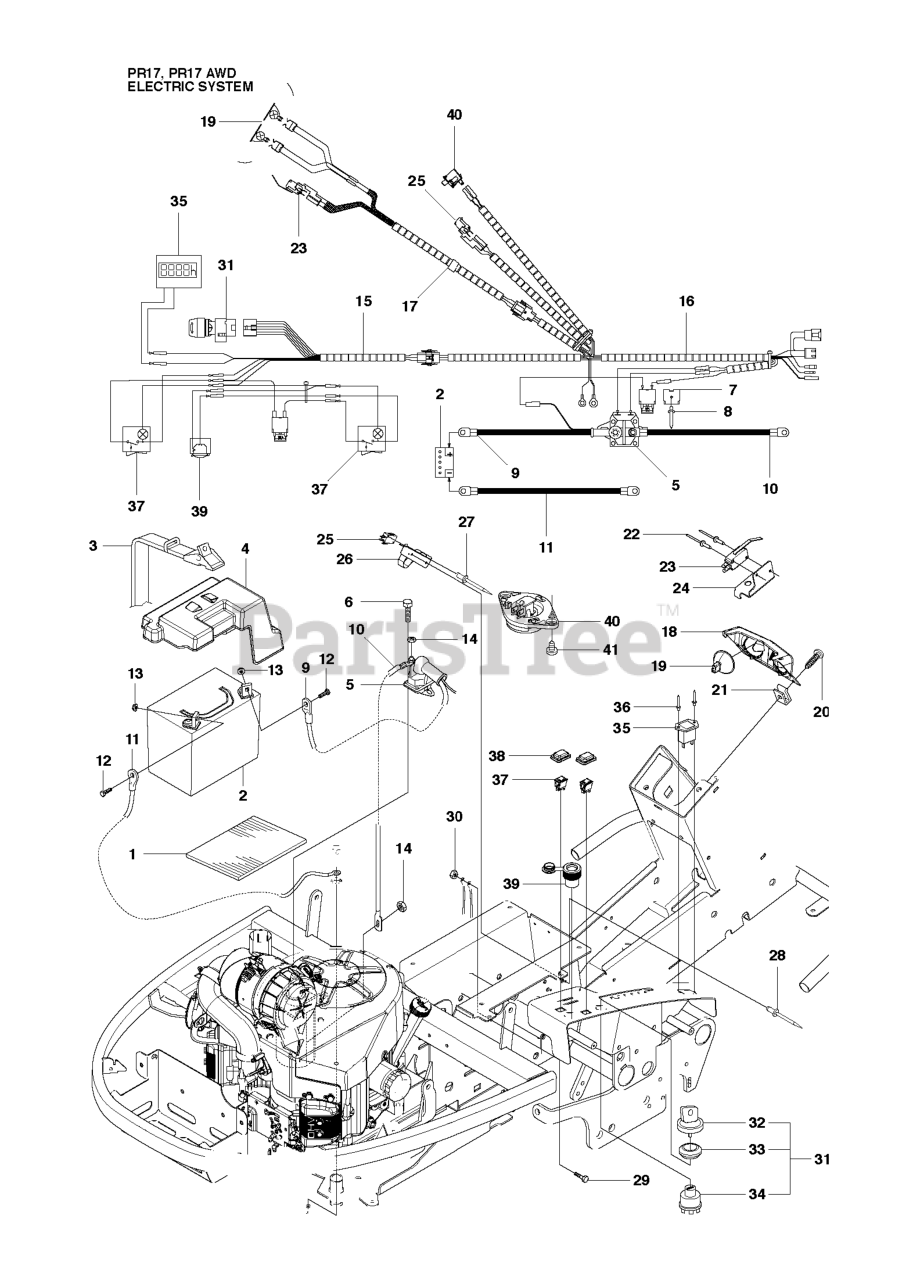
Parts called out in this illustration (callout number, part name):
9	CABLE
12	SCREW EHHM
15	WIRING CONTROL PANEL
23	RP MICRO SWITCH
25	%BRAKER
35	HOUR METER
40	ANTI-START SWITCH CPL
41	SCREW
